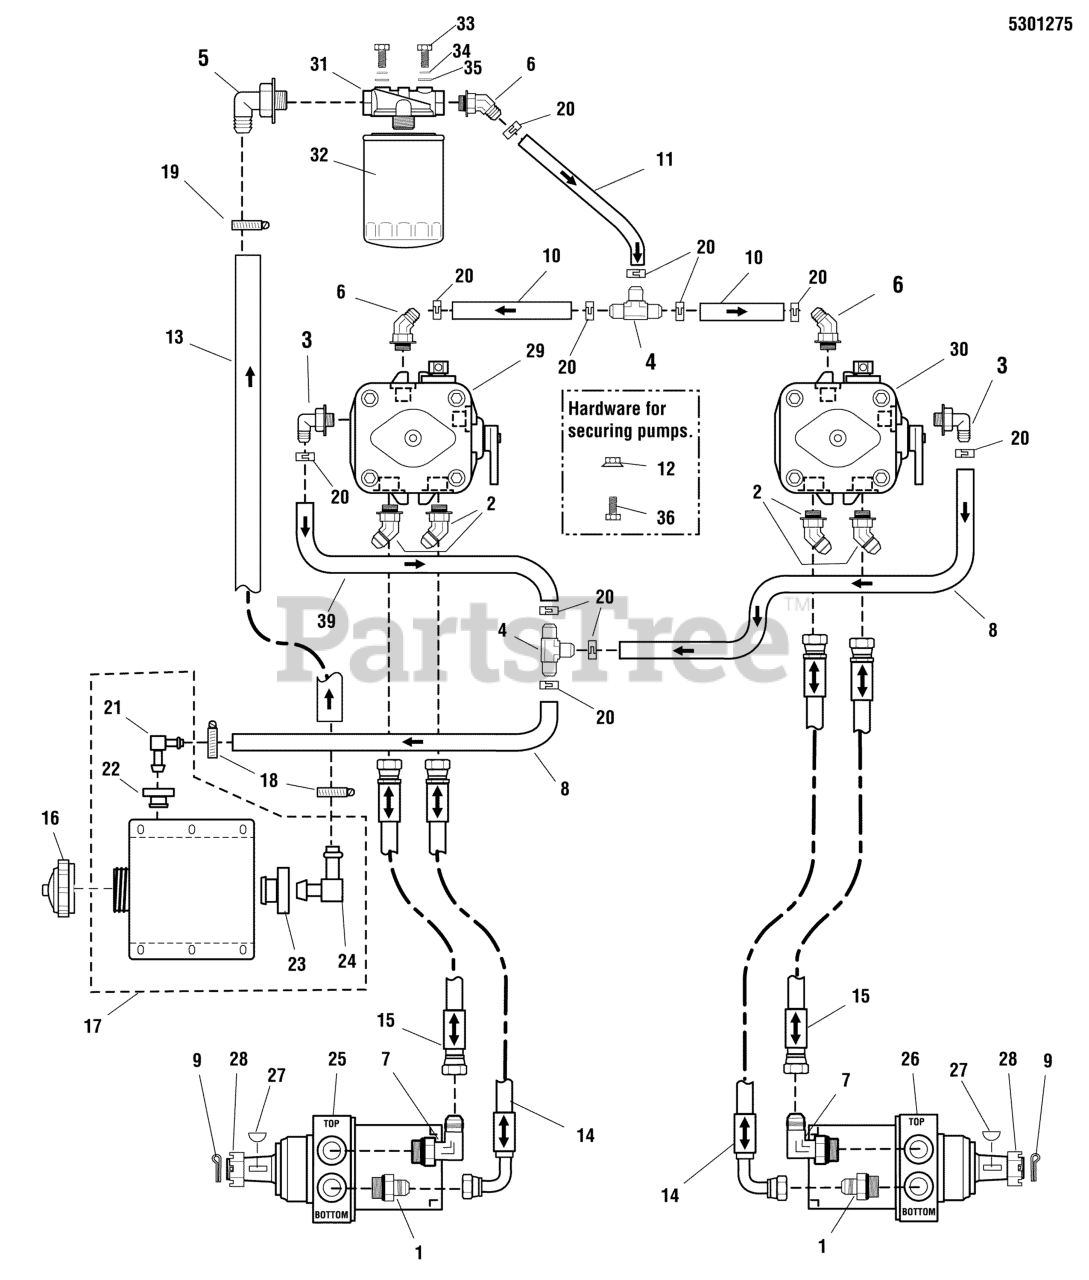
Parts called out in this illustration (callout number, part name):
1	ADAPTER, HYD.
2	FITTING, #8 JIC - #8 O-RING, 45 DEG.
3	ADAPTER, 90 DEG, 9/16-3/8 BARB
4	FITTING, TEE, 1/2 HOSE
5	ADAPTER, 90 DEG, 9/16-5/8 BARB
6	ADAPTER, 45 DEG, 9/16-3/8 BARB
7	FITTING, #10 ORING-#8 JIC, 90D
8	HOSE, 3/8" PUSH-LOCK, 22.00"
9	PIN, COTTER, 1/8 X 2
10	HOSE, 3/8" PUSH-LOCK, 6.00"
11	HOSE, 3/8" PUSH-LOCK, 8.00"
12	NUT, 3/8-16 HEX SERRATED FLANGE
13	HOSE, 5/8, PUSH-LOCK, 25.00
14	HOSE ASSEMBLY, (26.50)
15	HOSE ASSEMBLY, (22.50)
16	CAP, HYDRAULIC, SHIELDED VENT
17	TANK, HYDRAULIC, ASSEMBLY
18	CLAMP, #4 HOSE, STAINLESS
19	CLAMP, #10 HOSE, STAINLESS
20	CLAMP, HOSE
21	FITTING, ELBOW, 3/8" (SV)
22	BUSHING-FUEL TANK RED RUBBER
23	GROMMET (SV)
24	FITTING, ELBOW, 5/8" (SV)
25	WHEEL MOTOR, LH, 14.5 CI-TF0240LS080AAKZ
26	WHEEL MOTOR, RH, 14.5 CI-TF0240LS081AAKZ
27	KEY, WOODRUFF, #1008, 5/16 X 1
28	NUT, CASTLE 1-20
29	PUMP, HYD, 12CC - LH, PK-3HBQ-FV1F-XXXX
30	PUMP, HYD, 12CC - RH, PK-3KBQ-FV1F-XXXX
31	FILTER HEAD, HYDRAULIC
32	FILTER, OIL
33	BOLT, 1/4-20 X 3/4 GD5 YZ
34	WASHER, 1/4 SAE
35	WASHER, 1/4 LOCK
36	BOLT, 3/8-16 X 1-1/4" GD5 CZ
39	HOSE, Hydraulic, 3/8 X 5.00", Gray
